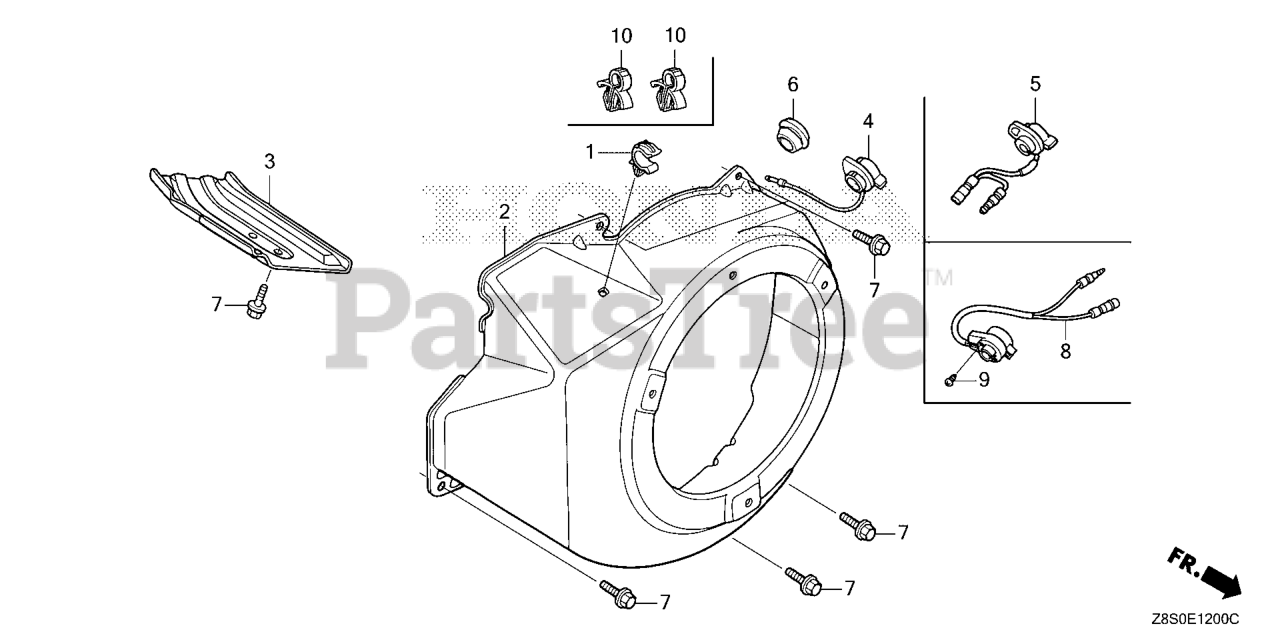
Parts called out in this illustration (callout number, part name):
1	CLIP, TUBE
2	COVER, FAN *NH1* (BLACK)
7	BOLT, FLANGE (6X12) (CT200)
8	SWITCH ASSY., ENGINE STOP
9	SCREW, TAPPING (3X6) (PO)
